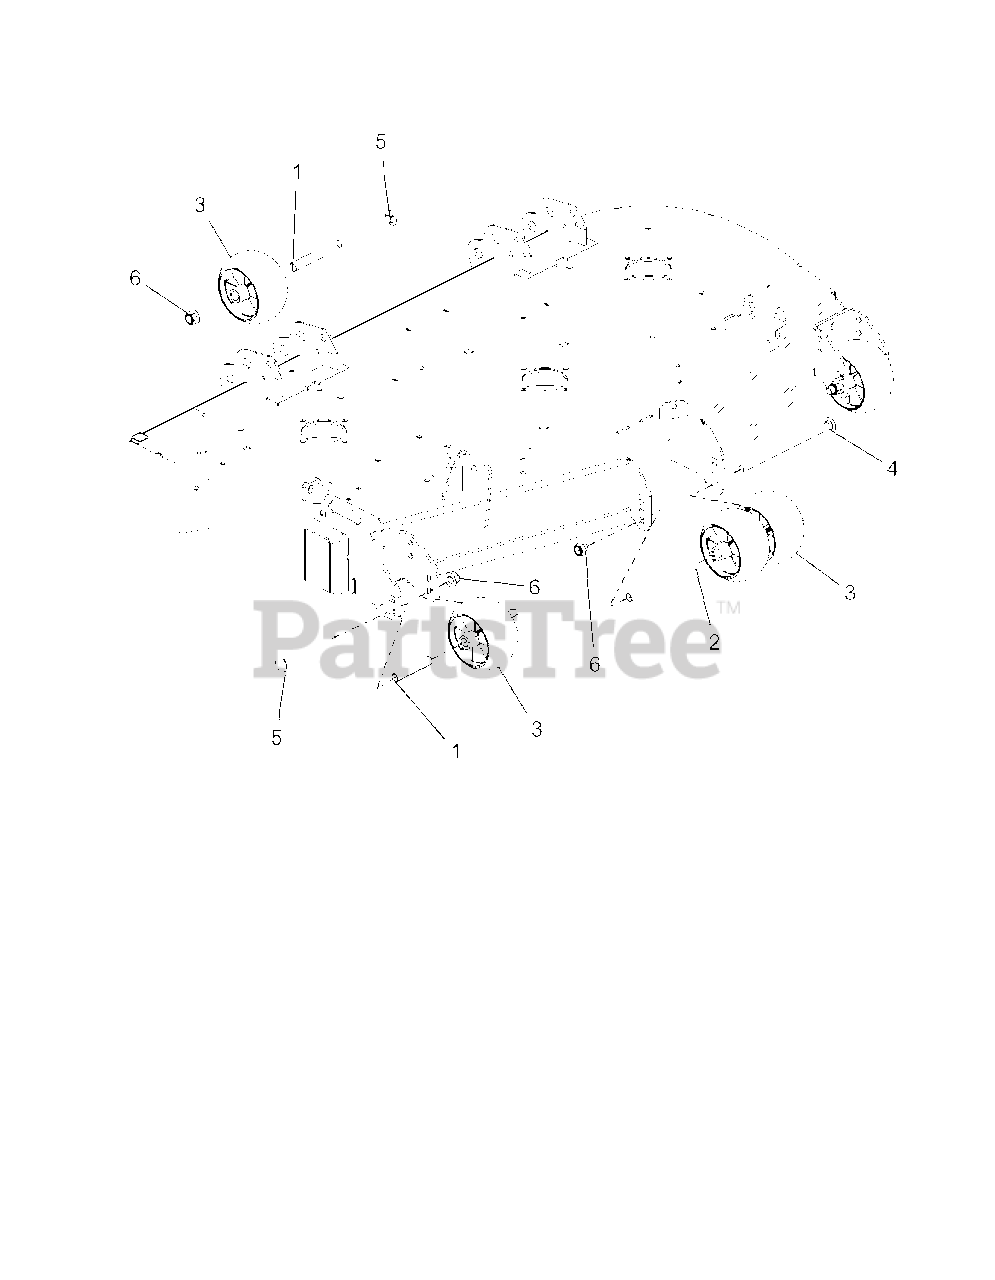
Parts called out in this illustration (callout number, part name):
1	SPACER, .510X.625X3.35
2	SPACER, .510 X .625 X 6.50
3	ANTI-SCALP WHEEL - 5X3 CTR
4	BLT-RDHDSQNK .50-13X8.50 Y
5	BLT-RDHDSQNK .50-13X5.00 G5 YWZC
6	NUT-LK-NYL-FLG .50-13 YWZC
